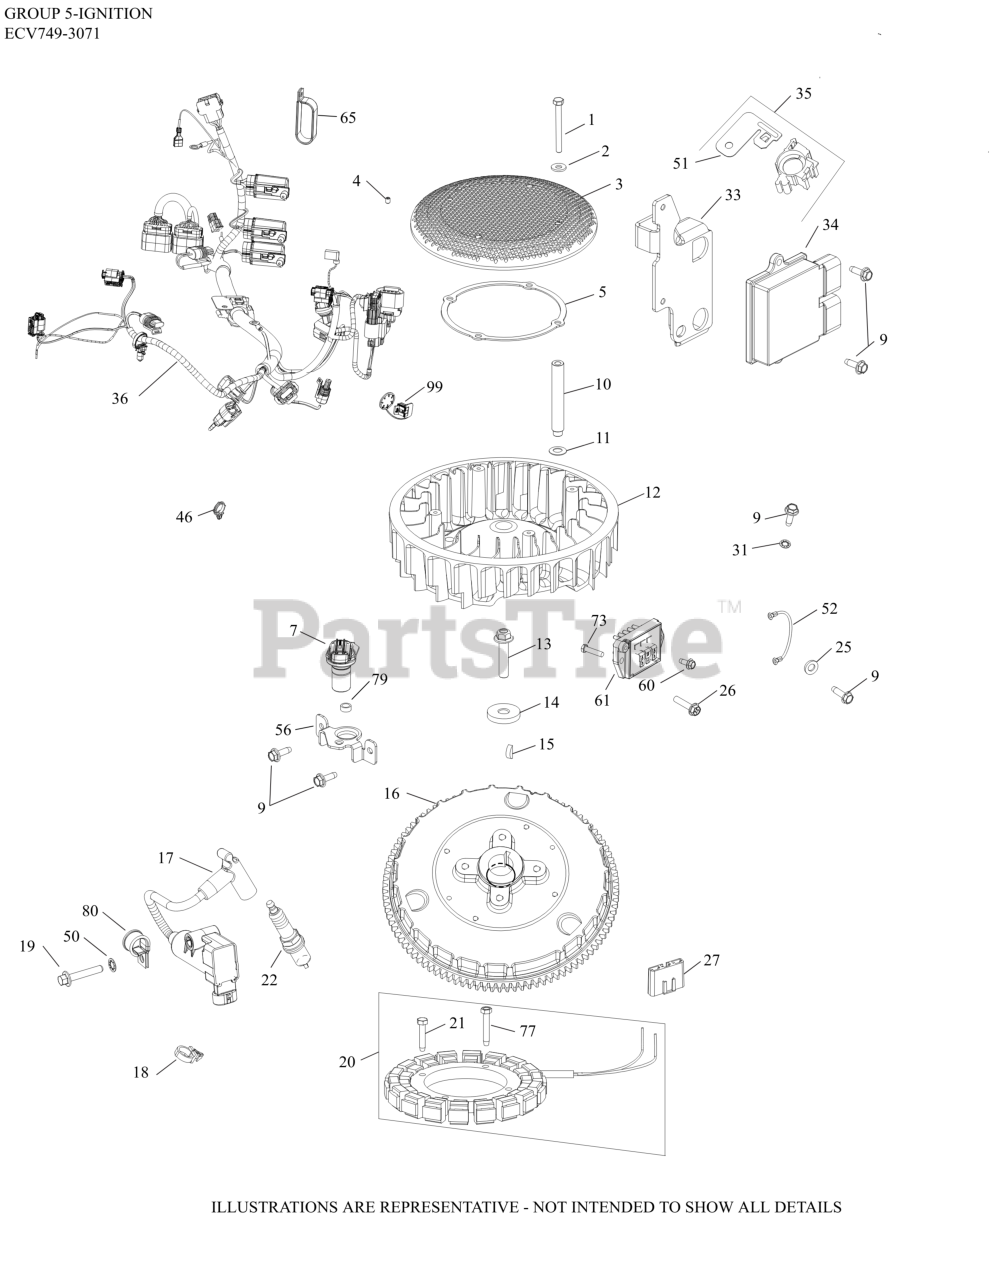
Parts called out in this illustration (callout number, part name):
1	SCREW, CAP M6X1.0X99.5
2	WASHER, FLAT 1/4" (O.D. 5/8")
3	SCREEN, GRASS
4	SCREW, SKT SET #10-24X1/4"
5	RING, SUPPORT
7	SENSOR, SPEED
9	SCREW, THREAD FORMING
11	WASHER, SPRING 10 MM
13	SCREW, FLG M10X1.5X45-USE 25 086 361-S
14	WASHER, FLAT 13/32"
15	KEY, 3/16" X 5/8"
16	FLYWHEEL, ASSEMBLY
17	COIL, IGNITION - EFI
19	SCREW, FLG (BLACK) M6X1.0X34
20	KIT, 15 / 20 AMP STATOR
21	SCREW, THREAD FORMING
22	SPARK PLUG, RFI
25	WASHER, FLAT 1/4" (O.D. 1/2")
26	SCREW, HEX FLANGE HI-LO
27	CONNECTOR
31	WASHER, INT TOOTH LOCK #10
33	BRACKET, ECU
34	MODULE, ECU
35	KIT, MOUNTING CLIP
36	HARNESS, WIRING ASSEMBLY
46	RETAINER, WIRE HARNESS
50	WASHER, INT TOOTH LOCK 1/4"
51	CLIP USE 25 154 21-S
56	BRACKET, SENSOR
60	SCREW, THREAD FORMING
61	REGULATOR, RECT (20-30AMP, FW W/OVP)
65	CLAMP, INSULATED DOUBLE
99	CAP, CONNECTOR (4-WAY, BLACK)
